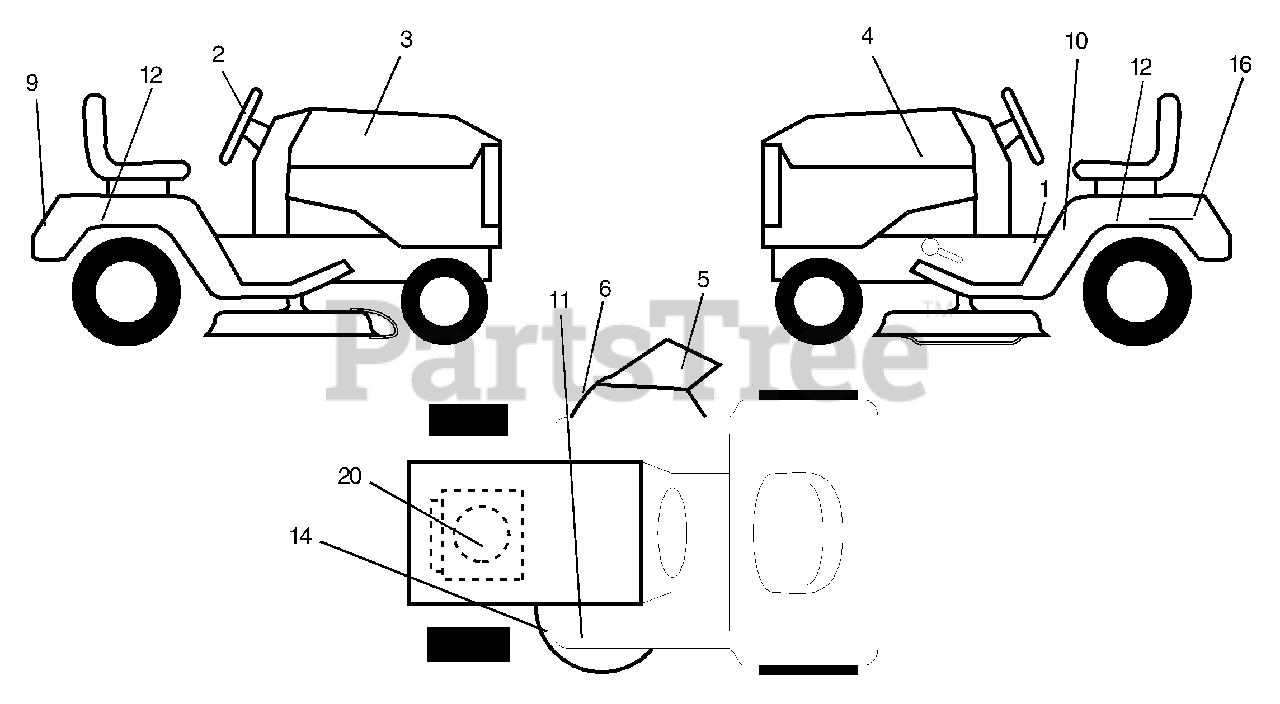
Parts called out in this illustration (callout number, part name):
1	Decal Instruction Operat English
2	Decal Steering
3	Decal Hood Rh
4	Decal Hood Lh
5	Decal Deck "B"
6	Decal Warning
9	Decal Fender Logo
10	Decal Danger English
11	Decal Clutch/brake
12	Decal Fender
14	Decal V-belt Schematic 42"
16	Decal Battery Danger/Poison
20	Decal HP Engine
